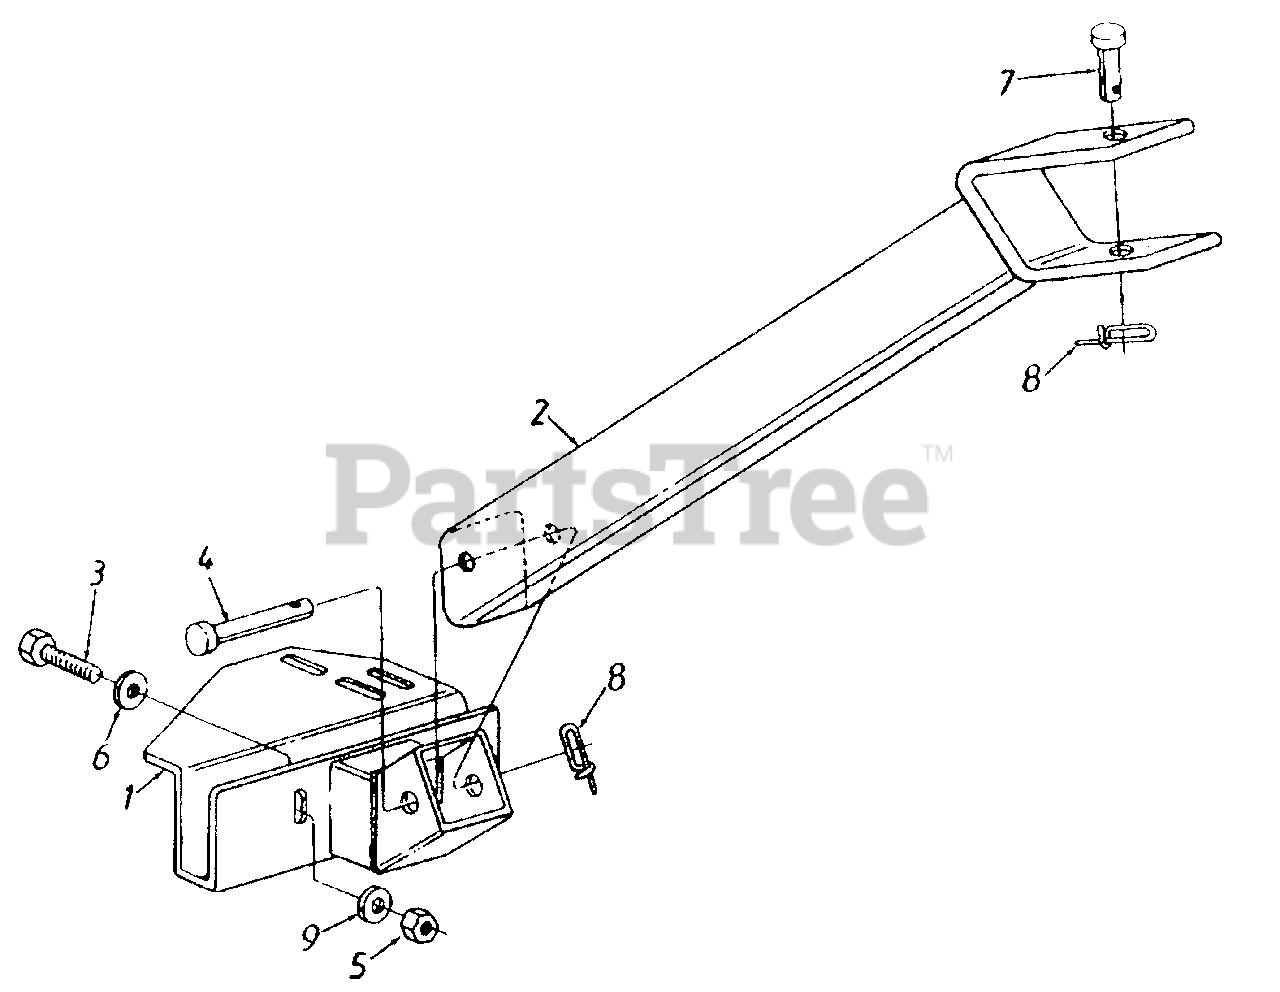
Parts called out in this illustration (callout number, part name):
4	Clevis Pin 2.4' Lg.
5	Hex Nut 3/8-16 Thd.
6	FL-Wash. .406" I.D. x 1.25" O.D. x .10"
7	Clevis Pin 4.62" Lg.
8	Spring Pin
9	L-Wash. 3/8" I.D.
